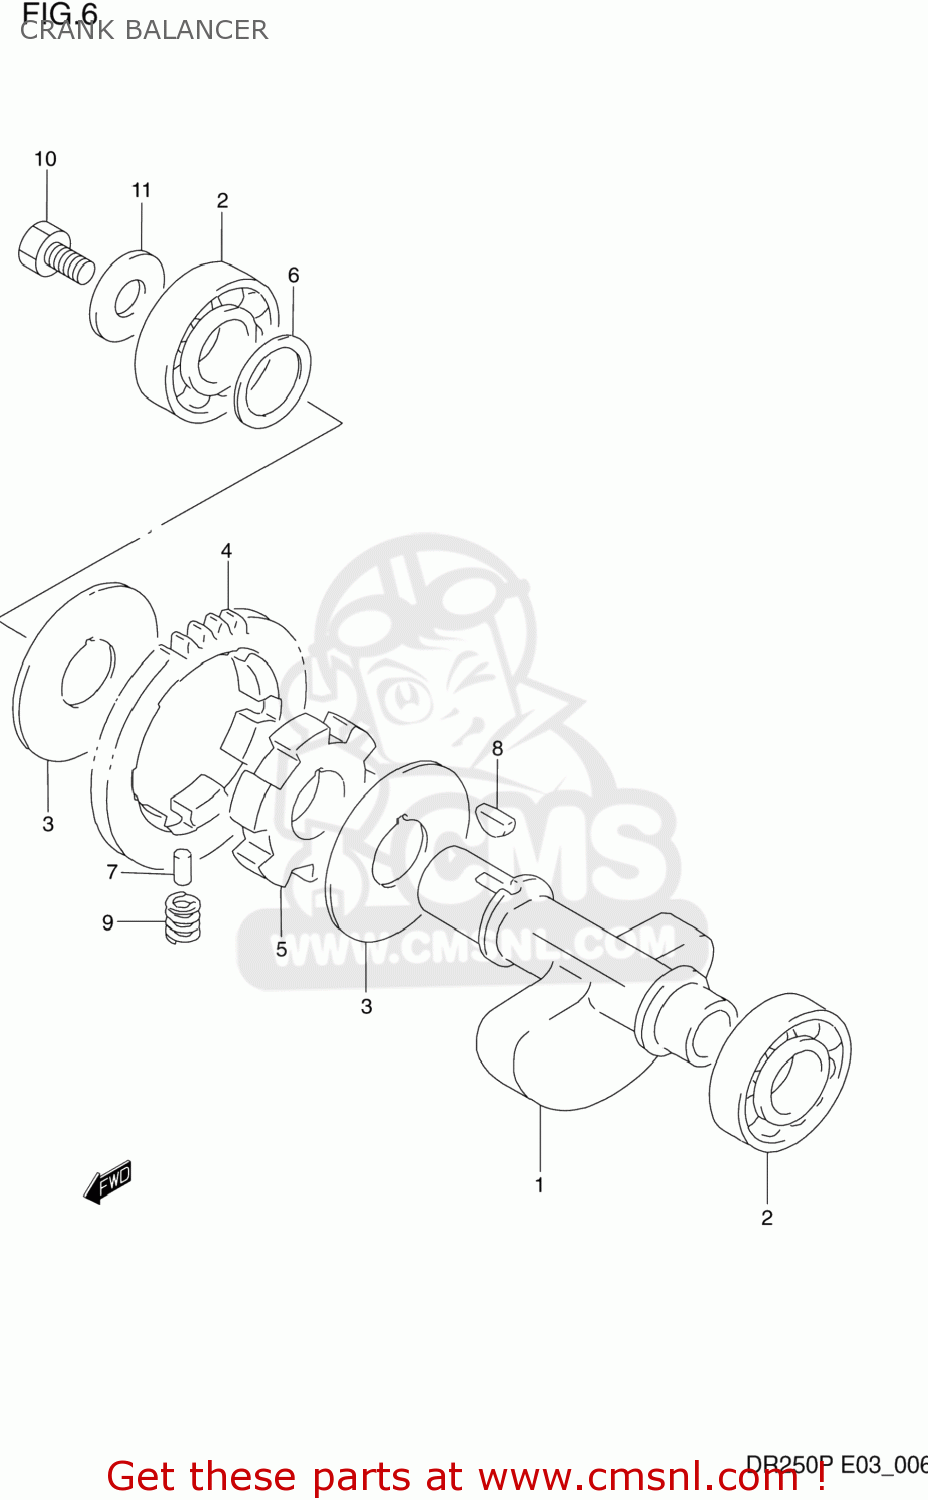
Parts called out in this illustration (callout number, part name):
1	BALANCER CRANK
2	BEARING(20X47X14)
3	WASHER
4	GEAR,CRANK BALANCER
5	RACE,CRANK BALANCER DRIVEN GEAR
6	THRUST WASHER
7	PIN
8	KEY 4MM
9	SPRING
10	BOLT
11	WASHER(10X28X2.2)
